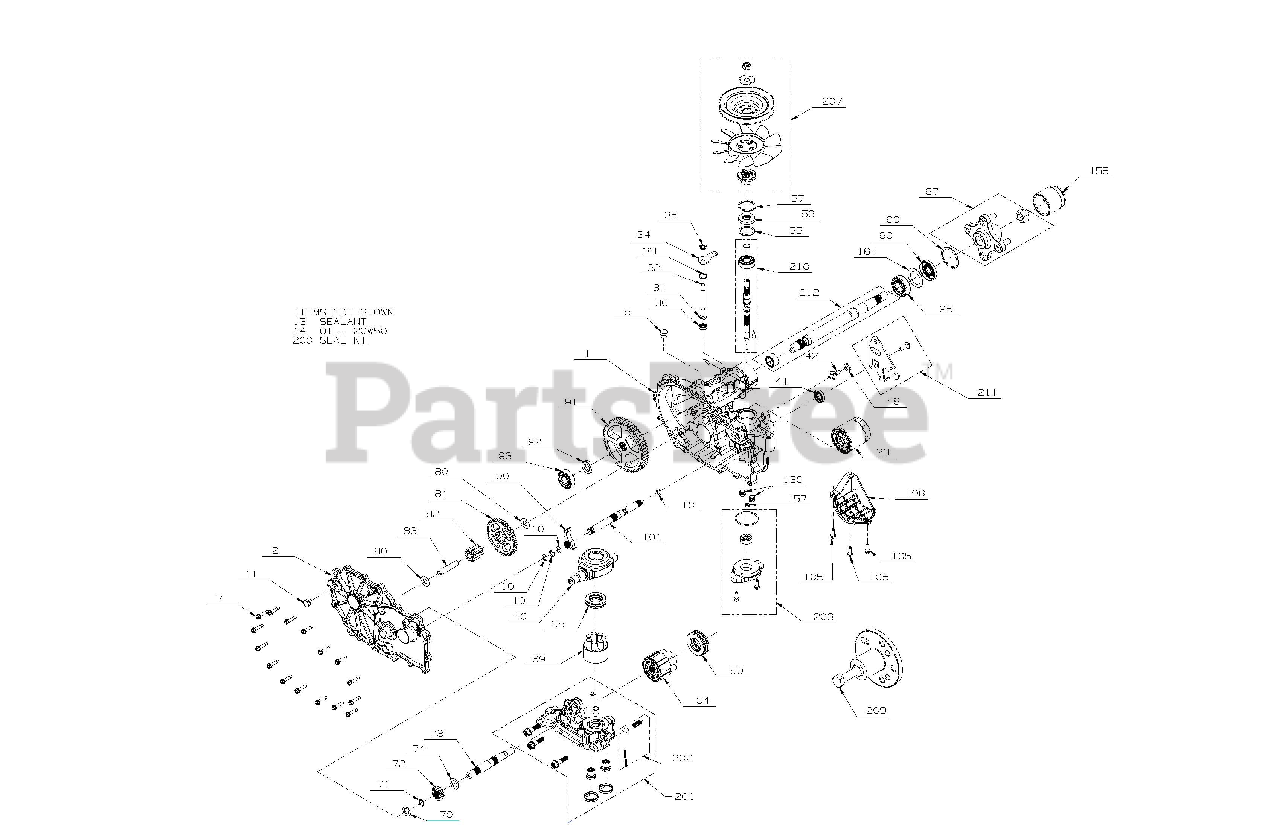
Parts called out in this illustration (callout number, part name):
1	KIT, MAIN HOUSING, LH, CHARGE, CONTROL
2	KIT, SIDE COVER LH
7	SCREW,HEX WASHER 1/4-20X1.125
13	SEALANT TUBE 10.1OZ.
23	OIL FILTER, TRANSMISSION
30	SEAL, LIP .375X.75X.25
31	RING. RETAINING
33	RING, RET .750
34	ARM, BYPASS
35	RING, RTNG .
40	TRUNNION, SWASHPLATE
41	SEAL, LIP 18X32X7
42	STUD. SHORT 5/16-24
48	SPACER
55	WASHER 1.23X1.56X.04
56	SEAL, LIP 17X40X7
57	RING, RET 1.56 INT
60	HG THRUST BEARING (51462)
64	HG 16CC CYLINDER BLOCK (71579)
65	BEARING. THRUST 30 X 52 X 13
69	ASSY, BLOCK 7 PISTON
70	WASHER .63X1.0X.05
71	RING, RET 62 EXT
73	SHAFT, MOTOR
74	WASHER .71 X 1.16 X .04
80	WASHER .5X1.0X.032
83	JACK SHAFT (PIN)
90	RING, RETAINING
95	BEARING, BALL 25.4 X 52 X 15
96	SEAL, LIP
97	KIT, HUB 4 BOLT
100	PAWL, BRAKE
101	KIT, BRAKE SHAFT
105	HFHCS 1/4-20X.75
106	HG FILTER GUARD LH (52247)
130	TUBE, CHARGE TRIPLE O-RING
157	KIT, GEROTOR SEAL
158	CAP, AXLE
164	WASHER, 1.355 X 2.035 X .021 FLAT
200	KIT, SEAL
201	KIT, CENTERSECTION, LH, CHARGE
202	KIT, CHARGE RELIEF
203	KIT, CHARGE RELIEF
207	KIT, FAN/PULLEY
209	HUB PULLER 4 BLT HYDGEAR 71459
210	INPUT SHAFT 2800 HYDGEAR 71442
211	KIT, CONTROL ARM
212	KIT, SHAFT AXLE
